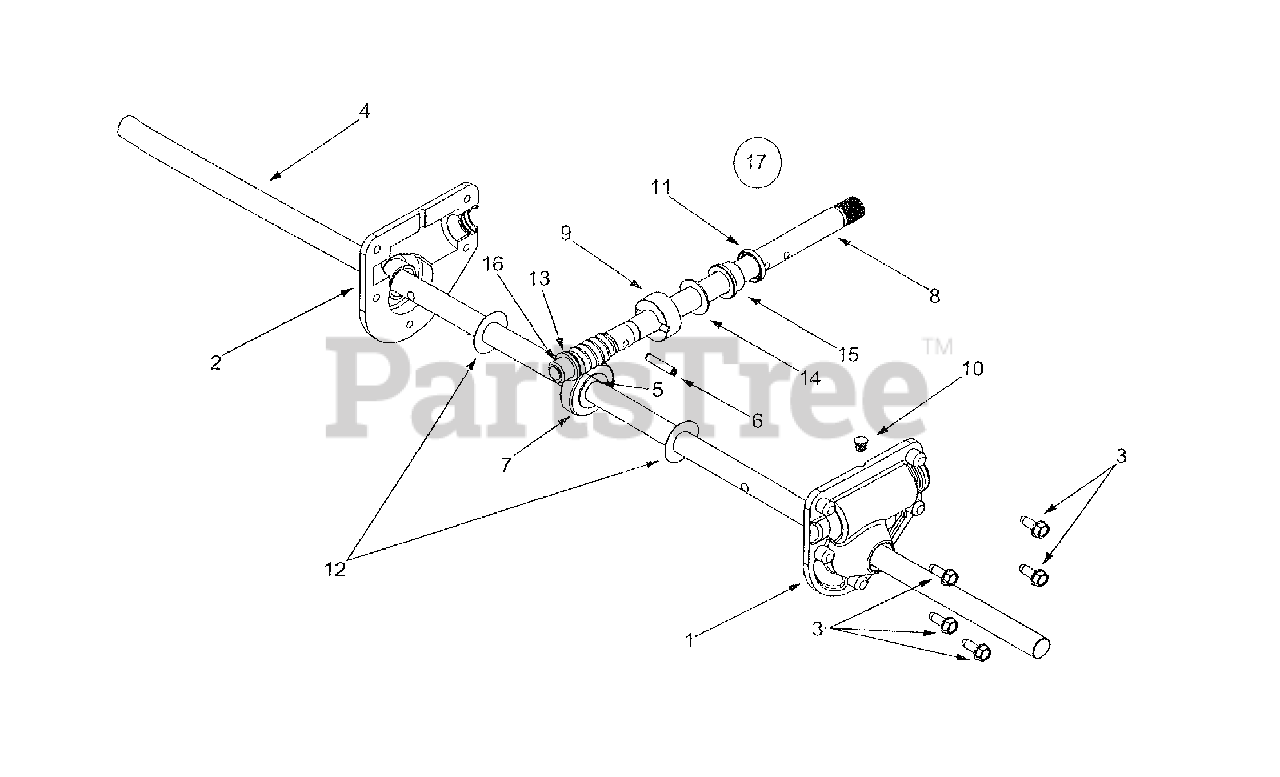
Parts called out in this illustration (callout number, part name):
1	RH Reducer Housing
2	LH Reducer Housing
3	Hex Screw 1/4-20 x .75
4	Spiral Axle 24"
4	Spiral Axle 26"
4	Spiral Axle 28"
6	Pin-Spiral
7	Worm Gear, 20T
8	Worm Shaft
9	Thrust Collar
10	Grease Plug
11	Grease Seal
12	Flat Washer .76 x 1.5 x .030
13	Flat Washer .508 x 1.0 x .020
14	Flat Washer .76 x 1.5 x .060
15	Flange Bearing .75 x 1.0 x .59
16	Flange Bearing .75 x 1.0 x .925
17	Ass'y. Complete 24"
17	Ass'y. Complete 26"
17	Ass'y. Complete 28"
